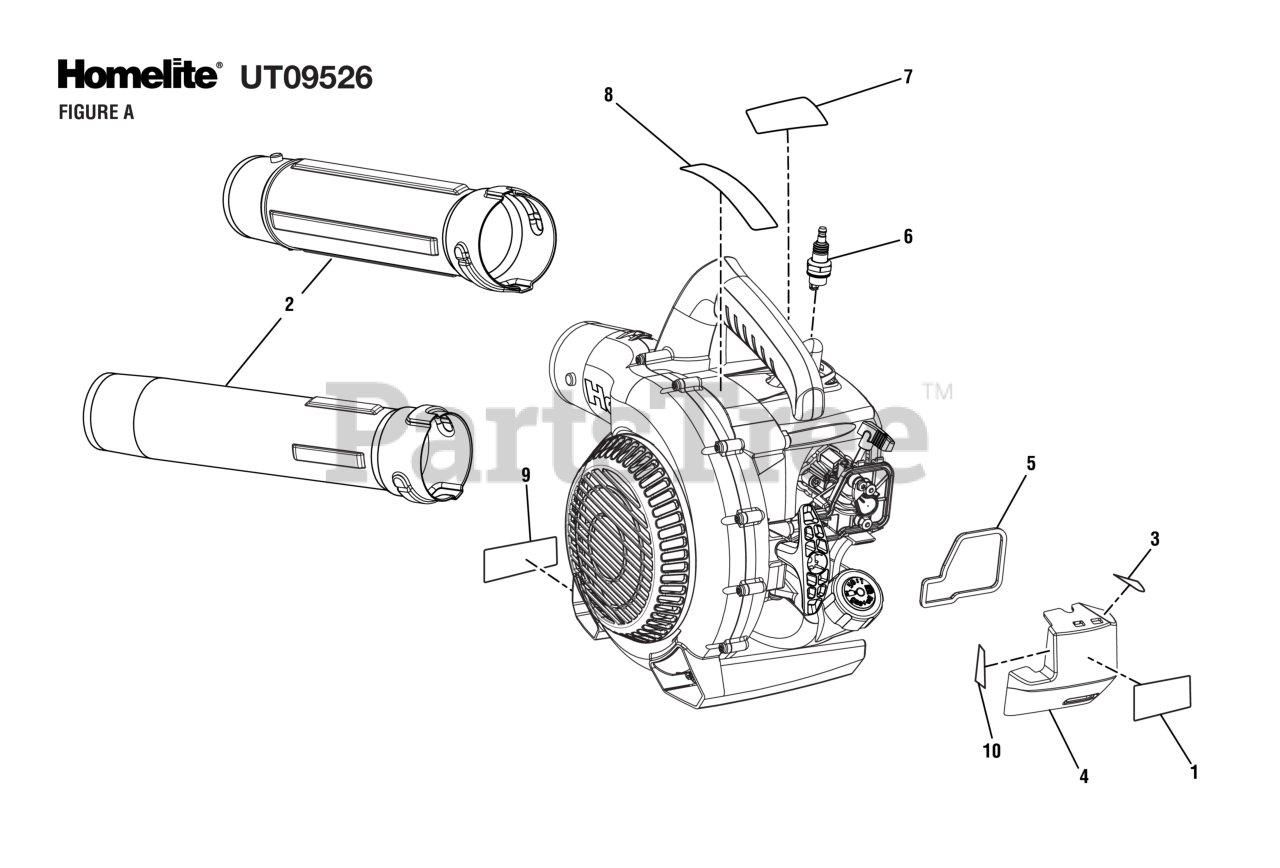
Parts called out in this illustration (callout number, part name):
1	Starting Instructions Label
2	Sweeper Nozzle & Upper Blower Tube Assembly
3	Throttle Label
4	Air Box Cover w/Label
5	Air Box Gasket
6	Spark Plug (Champion RCJ6Y)
7	Logo Label (Engine Shroud)
8	Warning Icon Label
9	Warning Label (Combustion)
10	Choke Label
